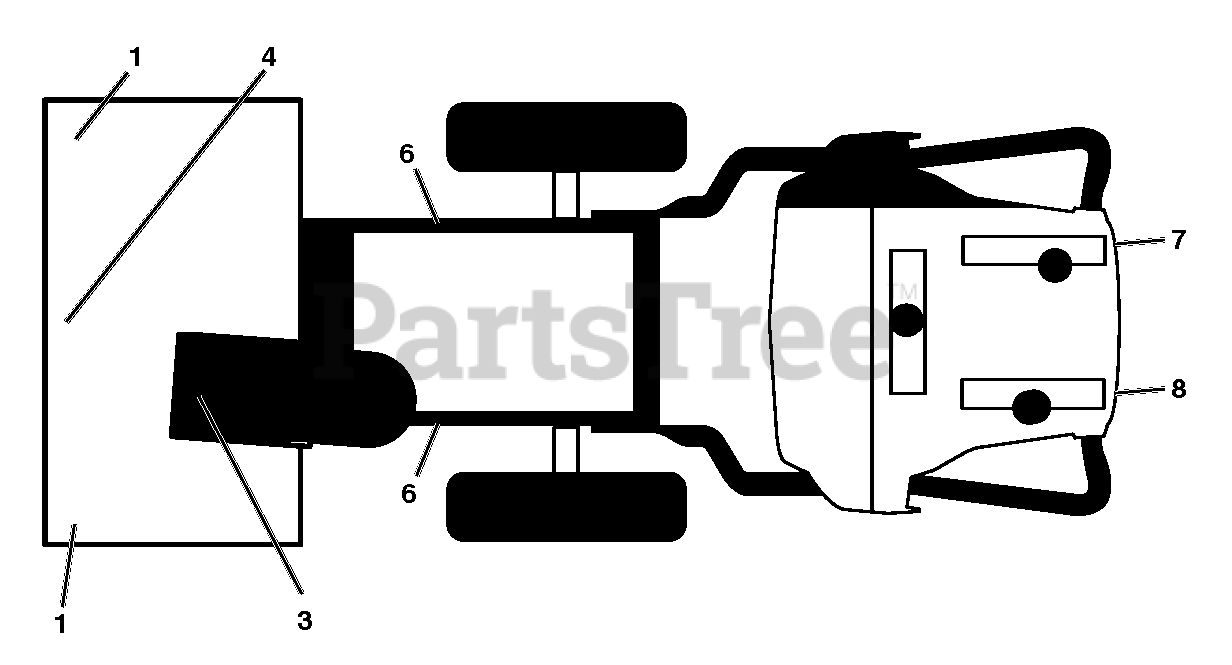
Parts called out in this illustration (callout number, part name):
1	DECAL.AUGER.SAFETY.
3	DECAL.CHUTE.SAFETY.EU/SC.17
4	DECAL.AUGER."
6	DECAL.BELT.GUARD.
